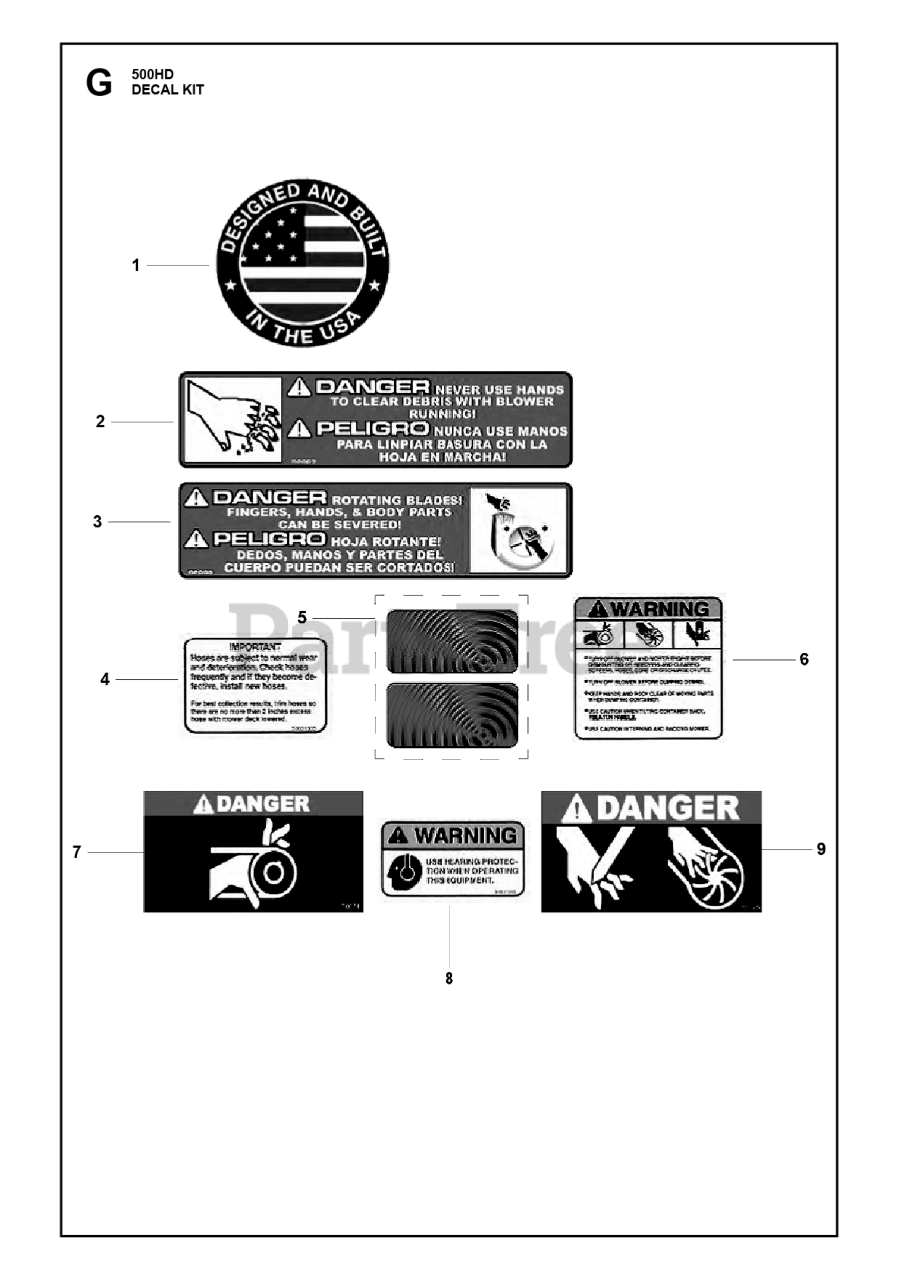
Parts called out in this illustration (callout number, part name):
1	DECALS
2	DECALS
3	DECALS
4	DECALS
5	DECALS
6	DECALS
7	DECALS
8	DECALS
9	DECALS
